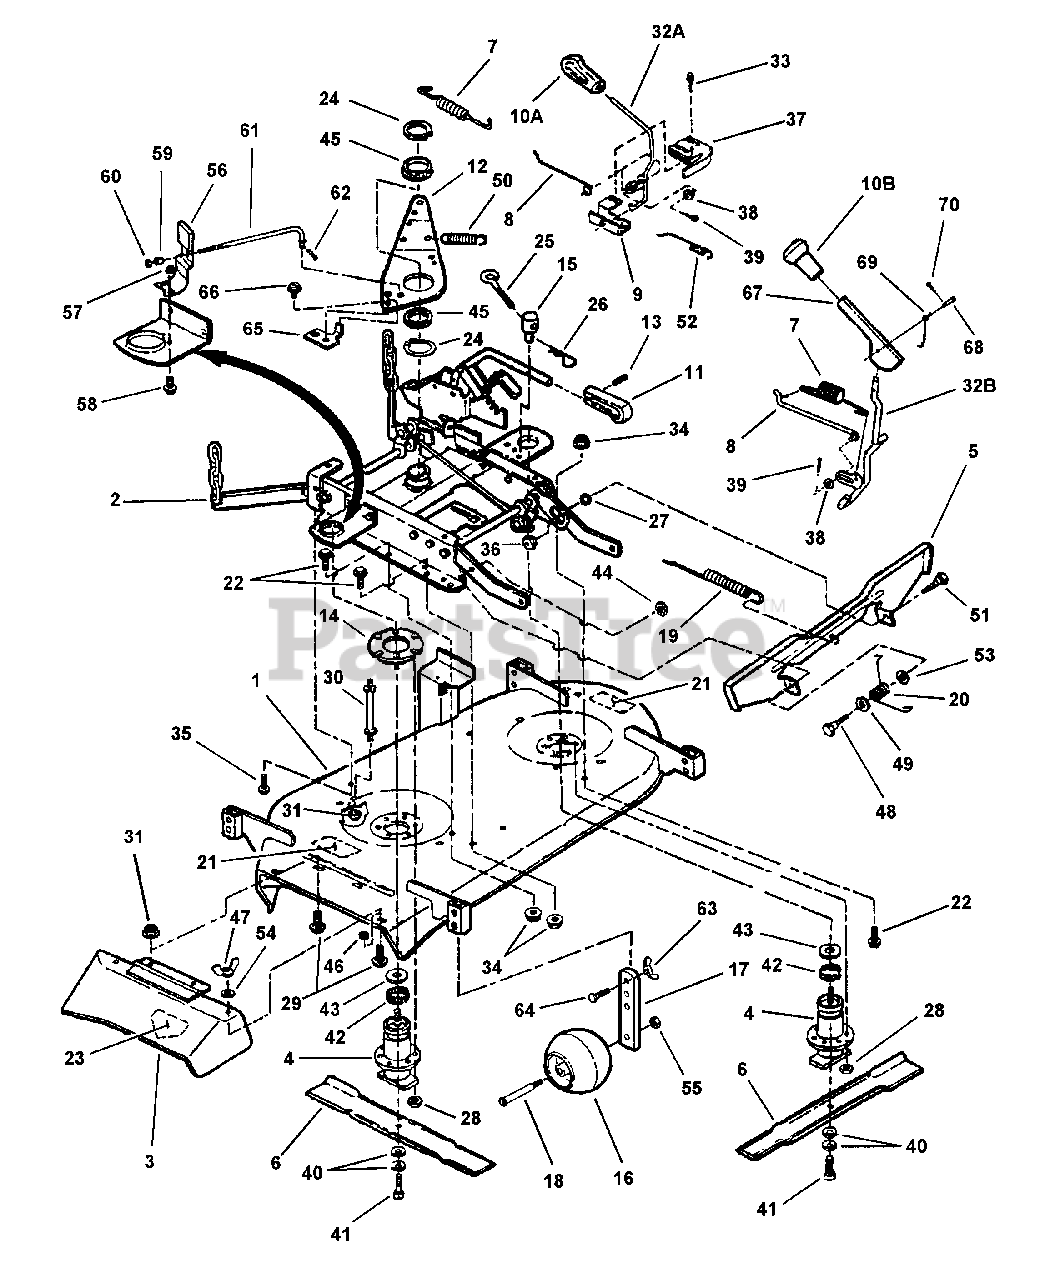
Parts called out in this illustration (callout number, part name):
1	WELDMENT, Deck
2	ASSEMBLY, Rail
3	ASSEMBLY, Side Chute
4	ASSEMBLY, Spindle
5	ASSEMBLY, Pedal
6	BLADE, 21" Standard. Lift
7	SPRING, Belt 5.1"
8	ROD, Idler
9	MOUNT, Handle
10A	GRIP, Handle
10B	GRIP, Handle
11	GRIP, Height Adjustment Lever
12	ARM, Idler
13	PIN, 3/16 x 3/4" Roll
14	ASSEMBLY, Spindle Ring
15	SWIVEL, Adjustable
16	WHEEL, Gage
17	POST, Anti-Scalp
18	BOLT, Gage Wheel, 3/8-16 x 3-3/8" Hex Head Shoulder
19	SPRING, Latch 5.875", .690" OD
20	SPRING, Pedal
21	DECAL, Caution
22	BOLT, 5/16-18 x 5/8" Hex Flange Lock
23	DECAL, Danger
24	RING, 2" External Retaining
25	BOLT, 5/16-18 x 3" Eye
26	HAIRPIN, 3/32 x 1-1/2"
27	WASHER, 3/8 Int. Tooth Lock
28	NUT, 3/8-16 Hex Lock
29	BOLT, 5/16-18 X 3/4" Short Neck Carriage, Grade 5
30	STUD, 5/16-18 x 3-1/2"
31	NUT, 5/16-18 Hex Fl. Lock
32A	LEVER, Blade Engage
32B	LEVER, Blade Engage
33	SCREW, #10-32 x 1" Hex Washer Self-Tap, Grade 2
34	NUT, 5/16-18 Hex Flge. Lock
35	SCREW, 5/16-18 x 5/8" Hex Washer Head, Self-Tap
36	ECCENTRIC, Leveling
37	SWITCH, Deck Interlock (NO)
38	WASHER, 1/4" Flat
39	PIN, 3/32 x 3/4" Cotter
40	WASHER, Cone
41	SCREW, 3/8-24 x 1" Hex Head Cap, Grade 5
42	RING, Tolerance
44	NUT, 3/8-24 Hex Lock
45	WASHER, 2" I.D., Nylon
46	RETAINER, 5/16" Bolt
47	WING-NUT, 5/16-18 Lock
48	BOLT, 3/8-24 x 9/16" Shoulder
49	WASHER, 1/2" Flat
50	SPRING, Return 5"
51	BOLT, 3/8-24 x 3/4" Shoulder
52	SPRING, Latch 3.6" x .515" OD
53	WASHER, 3/8" Flat
54	WASHER, 5/16" Flat
55	NUT, 3/8-16 Hex Center Lock
56	SPRING BRAKE PAD
57	NUT, 1/4-20 Hex Flange Lock
58	BOLT, 1/4-20 x 1/2" Hex Flange Lock
59	BUSHING, 3/8" Snap Plastic
60	NUT, 1/4-20 Hex Nyloc
61	LINK, Spindle Brake
62	COTTER-PIN, 1/16 x 1/2"
63	WING-NUT, 3/8-16 Nyloc
64	SCREW, 3/8-16 x 1-1/4" Hex Head Cap, Grade 5
65	EXTENSION, Idler Arm
66	SCREW, 1/4-20 x 3/8" Hex Washer Head, Self-Tap
67	HANDLE, Blade Engagement
68	PIN, 3/16 x 1" Clevis
69	SPRING, Torsion
70	PIN, 3/32 x 1/2" Cotter
